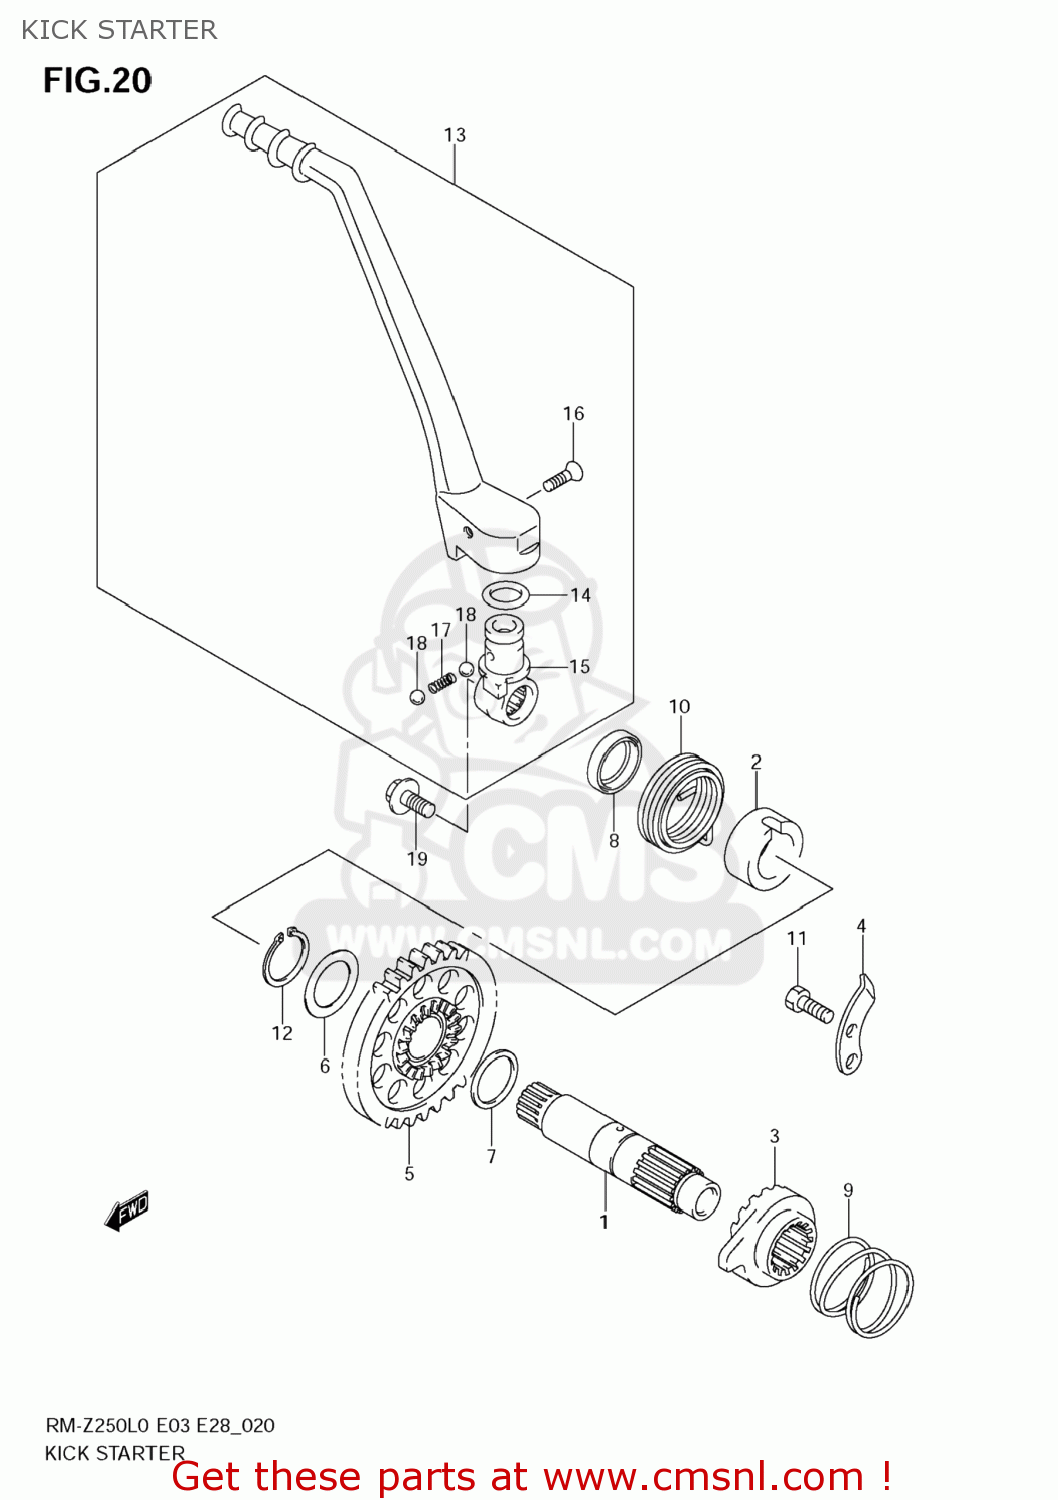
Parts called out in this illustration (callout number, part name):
1	SHAFT,KICK STARTER
2	GUIDE,KICK STARTER SFT SPRING
3	STARTER,KICK
4	GUIDE,KICK STARTER
5	GEAR,KICK STARTER DRIIVE
6	SHIM(18X26X0.5)
7	SHIM(18X22X1)
8	SEAL,OIL(18X30X8)
9	SPRING
10	SPRING
11	BOLT
12	CIRCLIP
13	LEVER ASSY,KICK STARTER
14	O RING,KICK STARTER
15	JOINT,KICK STARTER LEVER
16	SCREW(6X27.5)
17	SPRING
18	BALL
19	BOLT(8X14)
